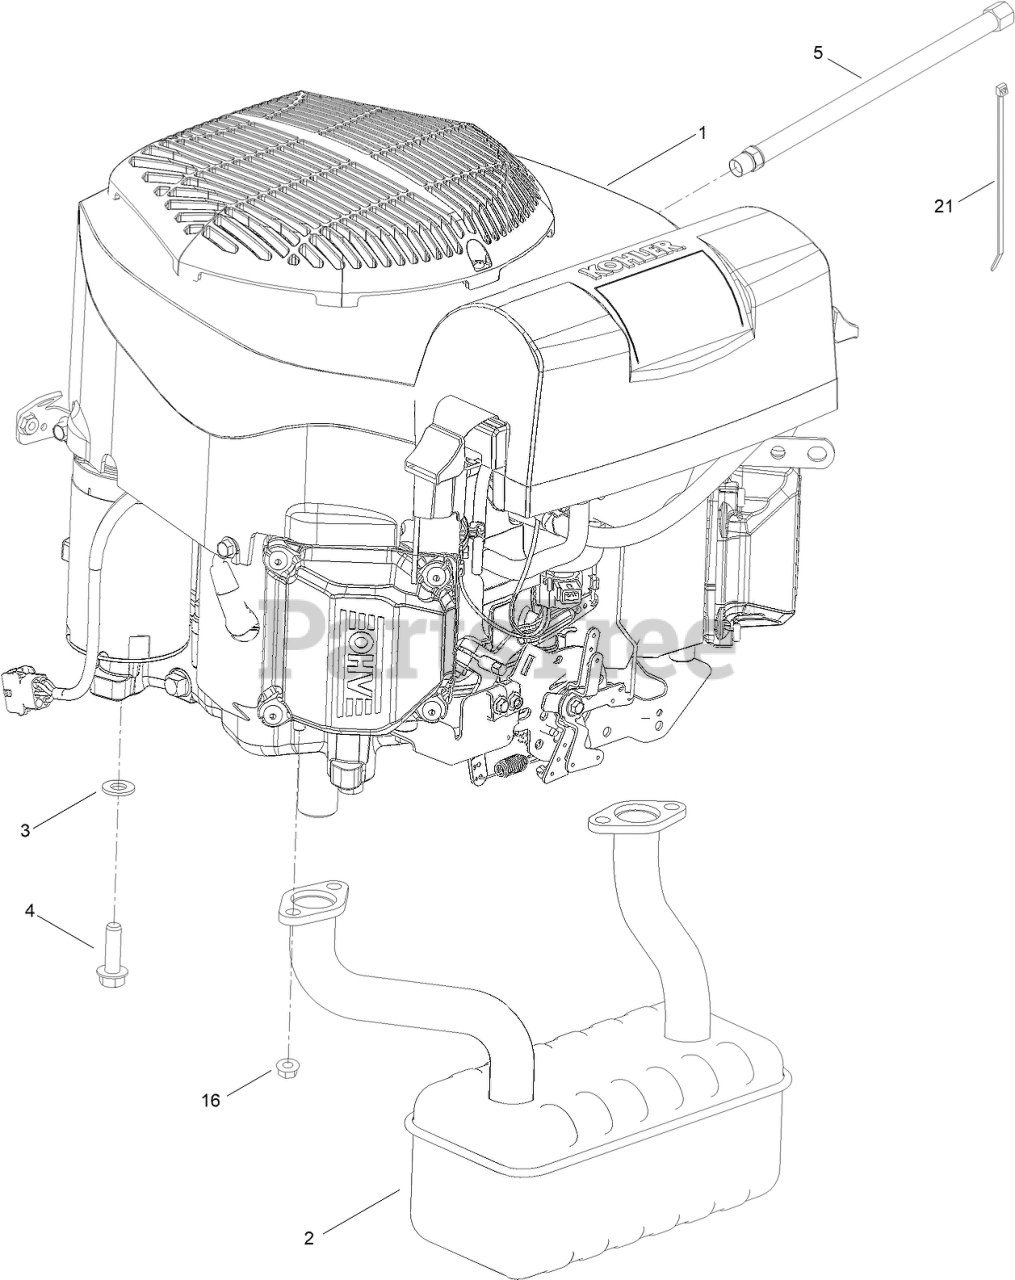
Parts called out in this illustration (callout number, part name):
2	MUFFLER
3	WASHER-FLAT
4	SCREW-THD
5	HOSE-DRAIN, OIL
16	NUT-HF
21	TIE-CABLE
